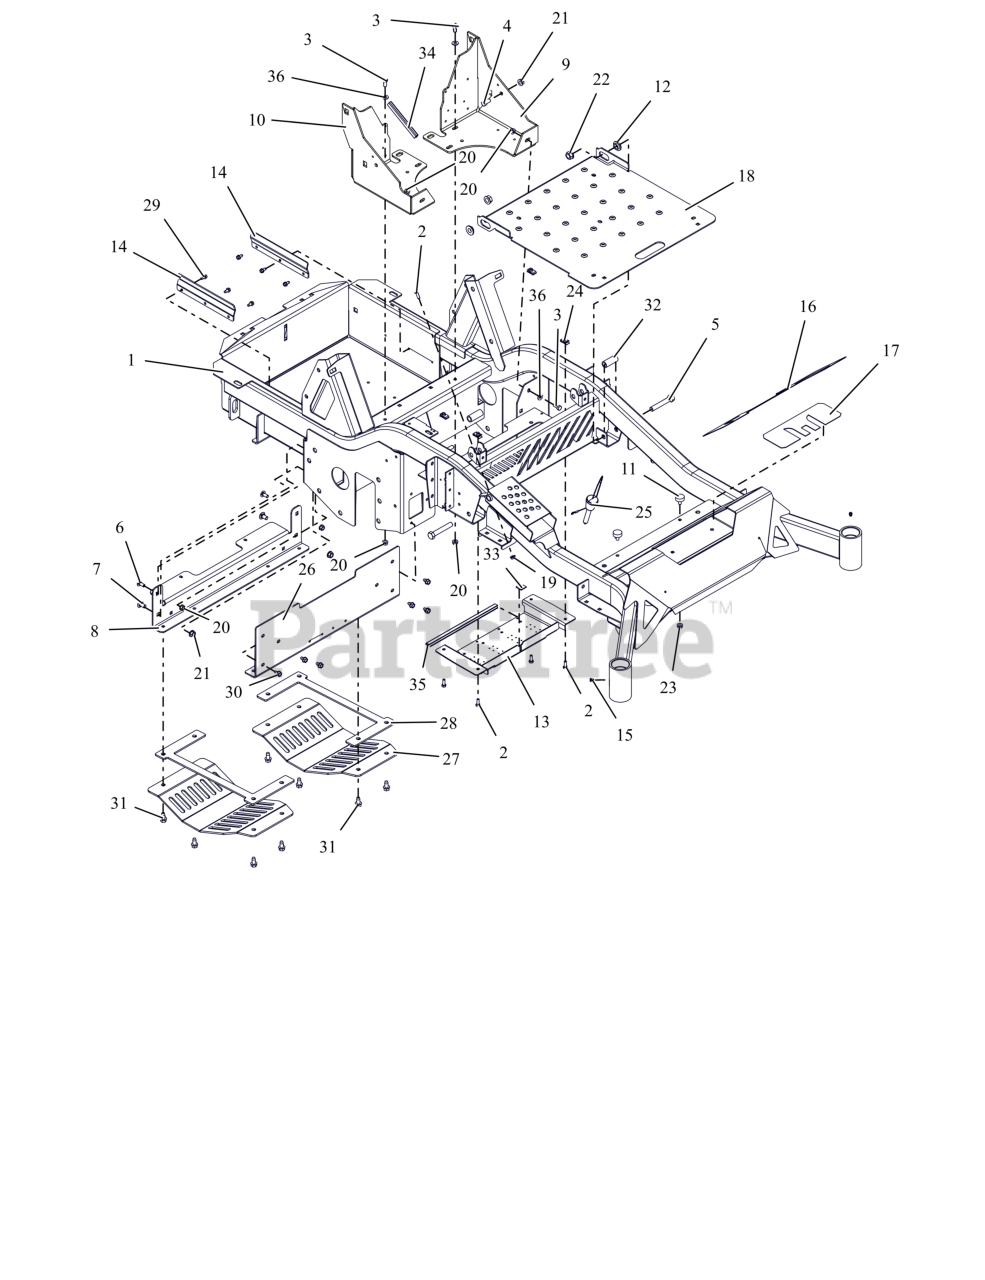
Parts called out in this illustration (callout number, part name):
1	KIT,EV FRAME(LG)W/DECALS-A
2	BLT, HEX .25-20X.75 G5 ZCC
3	BLT,HEX .31-18X.75 G5 ZCC
4	BLT,HEX .38-16X.75 G5 ZCC
5	BLT, HEX .50-13X3.00 G5 ZCC
6	BLT, RHSSN.31-18X.750 G5 ZCC
7	BLT, RHSSN .38-16X.75 G5 ZCC
8	BRKT, SKID PLATE MTG. (ORANGE)
9	BRKT, SUPPORT ROPS -LH (ORANGE)
10	BRKT, SUPPORT ROPS-RH (ORANGE)
11	BUMPER, RUBBER
12	BSHG-FLG .515X.750X.395X1.120
13	COVER, BOTTOM ACCESS -OPEN (ORANGE)
14	DEFLECTOR, BATTERY -EV (ORANGE)
15	FTG, .25-28 FLUSH MNT GREASE
16	GRIP, FRONT
17	GRIP, TAPE FRONT
18	PANEL, ACCESS
19	NUT-LK-CTR-FLG .25-20 ZC120
20	NUT,LK-CTR-FLG .31-18 GF ZCC
21	NUT-LK-CTR-FLG .375-16 GF ZCC
22	NUT-LK-CTR-FLG .500-13 GG ZCC
23	NUT,SPNLK-FLG .31-18 G5 ZCC
24	NUT-RTNR .25-20X.56
25	PIN- MAGNETIC .50X2.70
26	PLATE, FRONT FRAME (ORANGE)
27	PLATE, SKID (BLACK)
28	PLATE, SKID TENSION (BLACK)
29	SCR-TAP .25-20X.50 HWH ZCC
30	SCR,TAP .312-18X.50 HWH TR ZCC
31	SCR,TAP .375-16X.75 HWH TR ZCC
32	SPACER, .515X.75X1.83
34	STRIP, COWL
35	STRIP, COWL
36	WSHR, FLT .312X.734X.065 ZCC
